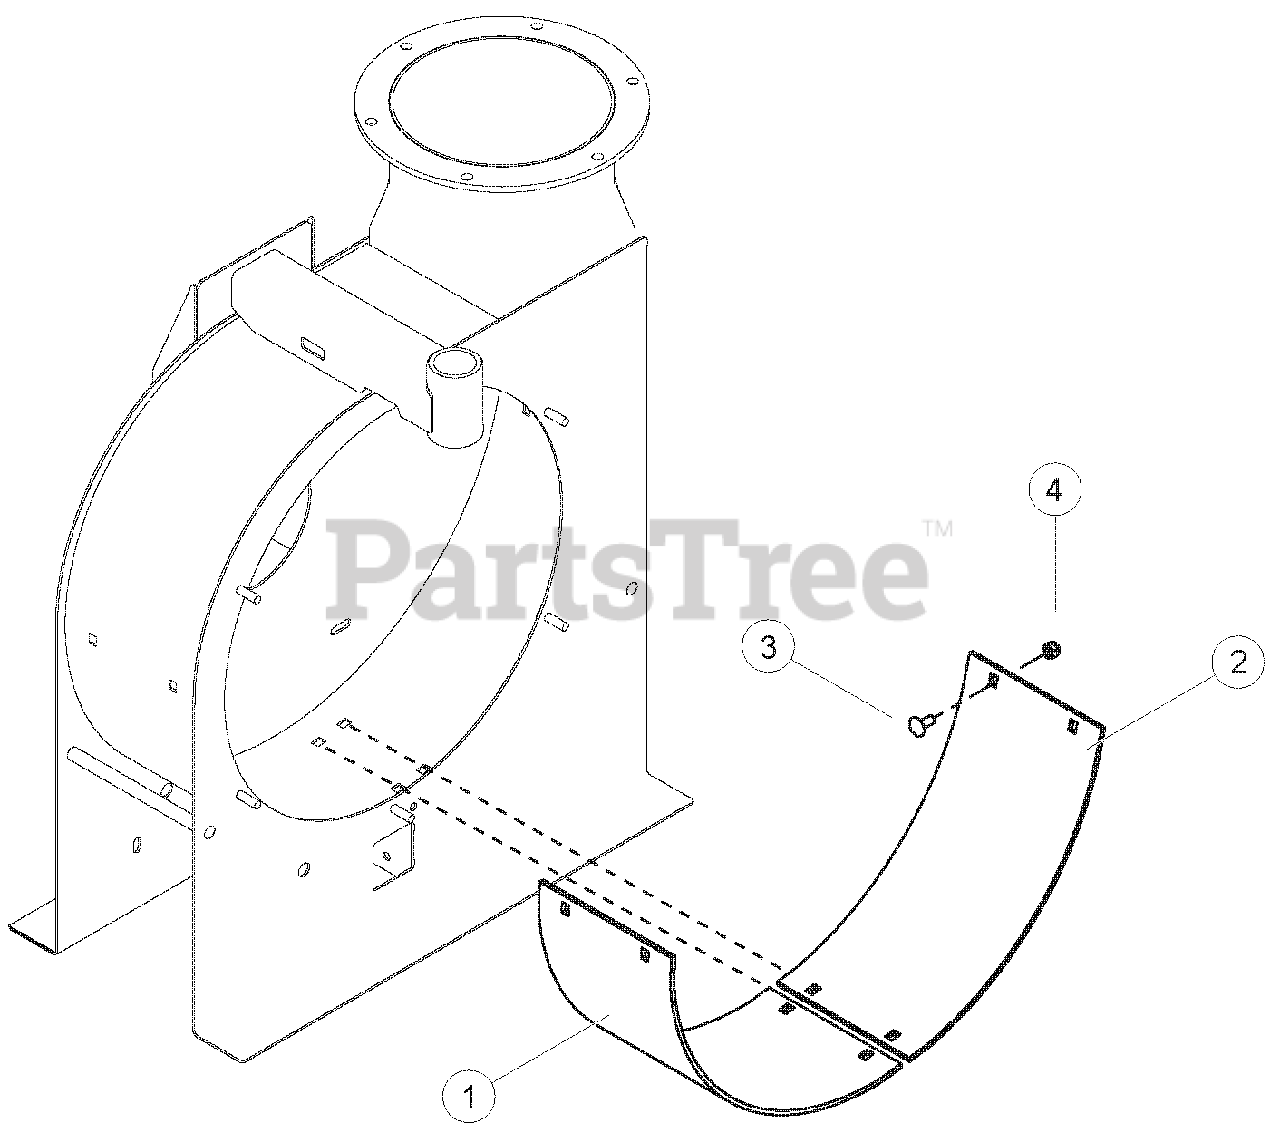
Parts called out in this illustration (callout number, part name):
1	LINER, WEAR
2	LINER, WEAR
3	BOLT, 5/16 X 3/4 CRG
